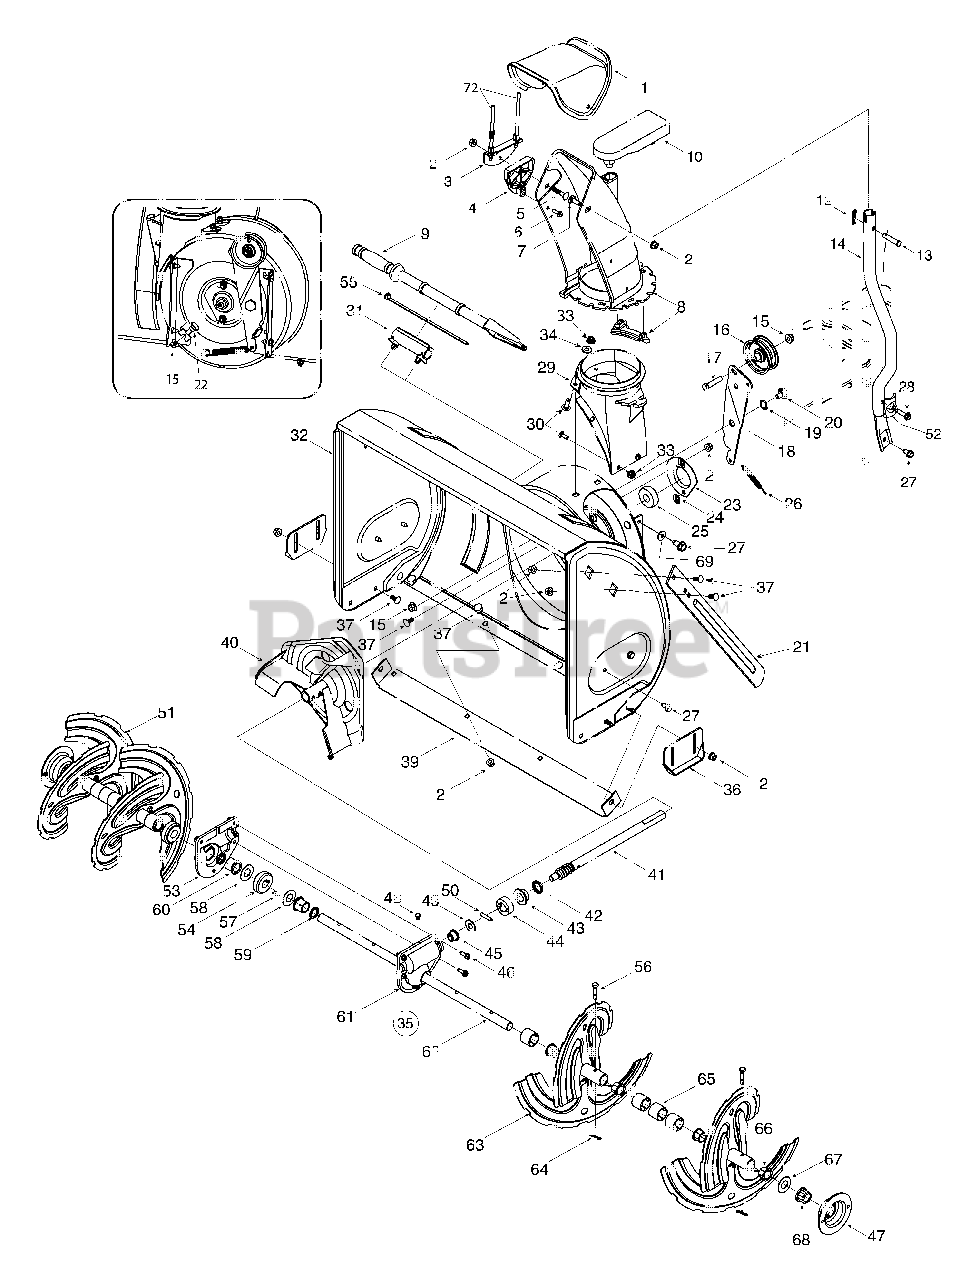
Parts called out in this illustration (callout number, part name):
1	Upper Chute
2	Flange Lock Nut, 5/16-18
4	Chute Tilt Cable Guide
5	Carriage Bolt, 5/16-18 x 1.50
6	Hi-Lo Screw, 1/4-15x 0.75
7	Carriage Bolt, 5/16-18 x 1.0
8	Lower Chute Assembly, Includes flange keepers
8	Chute, Keeper Flange
9	Clean-Out Tool
10	Kit, Rotation Pulley & Cable
12	Cotter Pin
13	Clevis Pin
16	Flat Idler Pulley
17	Hex Bolt, 3/8-16 x 1.75
19	Wave Washer
20	Shoulder Screw
22	Shoulder Screw
23	Bearing Housing
24	Push Nut
25	Ball Bearing
26	Extension Spring
27	AB Screw, 5/16-12 x 0.75
28	TT Screw, 5/16-18 x 1.750
29	Chute Adapter
30	Carriage Screw, 1/4-20 x 0.75
31	Clean-out Tool M tg. Bracket
33	Flange Lock Nut, 1/4-20
34	Flat Washer
35	Gearbox Assembly Complete
37	Carriage Bolt
41	Worm Shaft
42	Oil Seal
43	Flange Bearing
44	Thrust Collar
45	Flange Bearing
46	TT Screw, 1/4-20 x 0.75
49	Flat Washer
50	Dowel Pin
52	Handle Tab
53	Reducer Hsg.-RH (Incl Ref. 59-60)
54	Worm Gear, 20T
55	Cable Tie
56	Shear Pin
57	Key
58	Flat Washer
59	Oil Seal
60	Flange Bearing
61	Reducer Hsg.-LH (Incl Ref. 59-60)
62	Auger Axle
64	Bow Tie Cotter Pin
65	Spacer
66	Flange Bushing
67	Flat Washer
68	Hex Flange Bearing
69	Bell Washer
72	Cable, Chute Deflector
